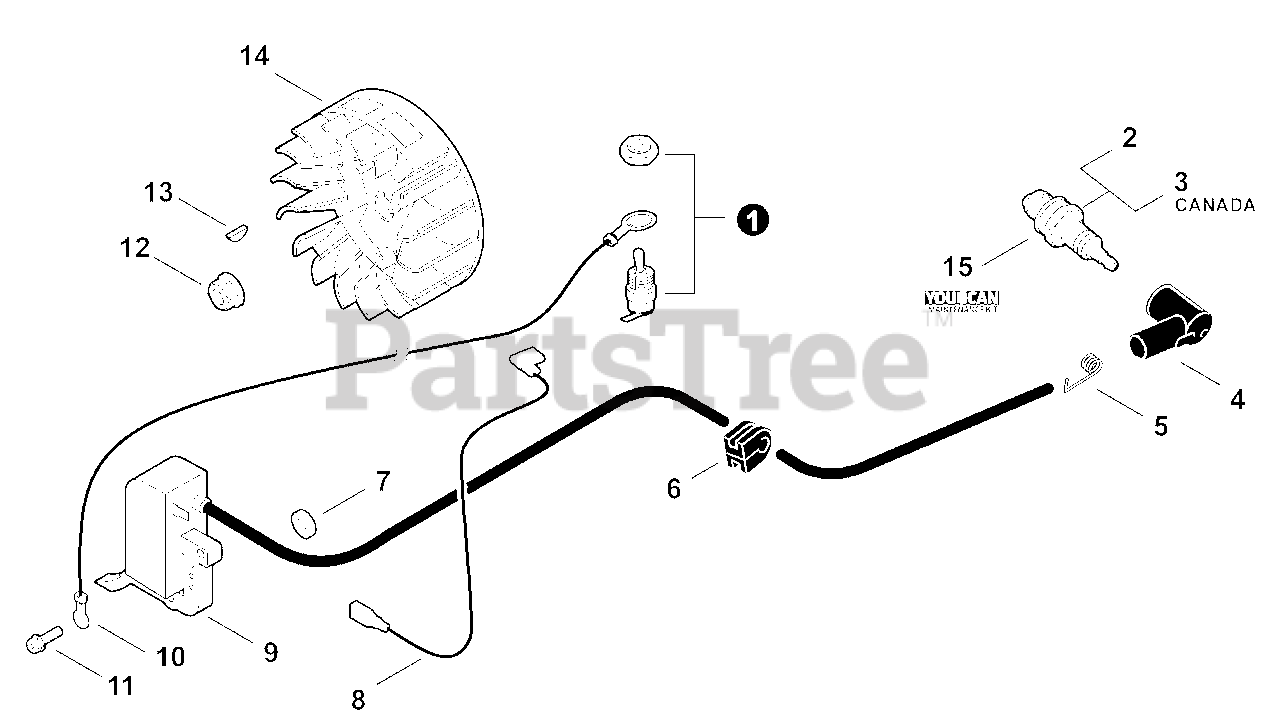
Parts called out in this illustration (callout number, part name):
1	SWITCH, ON-OFF
2	SPARK PLUG - BPM8Y
3	SPARK PLUG - BPMR8Y
4	CAP, SPARK PLUG
5	TERMINAL, SPARK PLUG
7	WASHER 5.2×12×3
8	LEAD - IGNITION L= 95
9	COIL, IGNITION
10	LEAD - GROUND L= 100
11	SCREW 5×22
12	NUT, FLANGE M8
13	KEY, WOODRUFF
14	FLYWHEEL
15	TUNE-UP KIT - YOUCAN™
